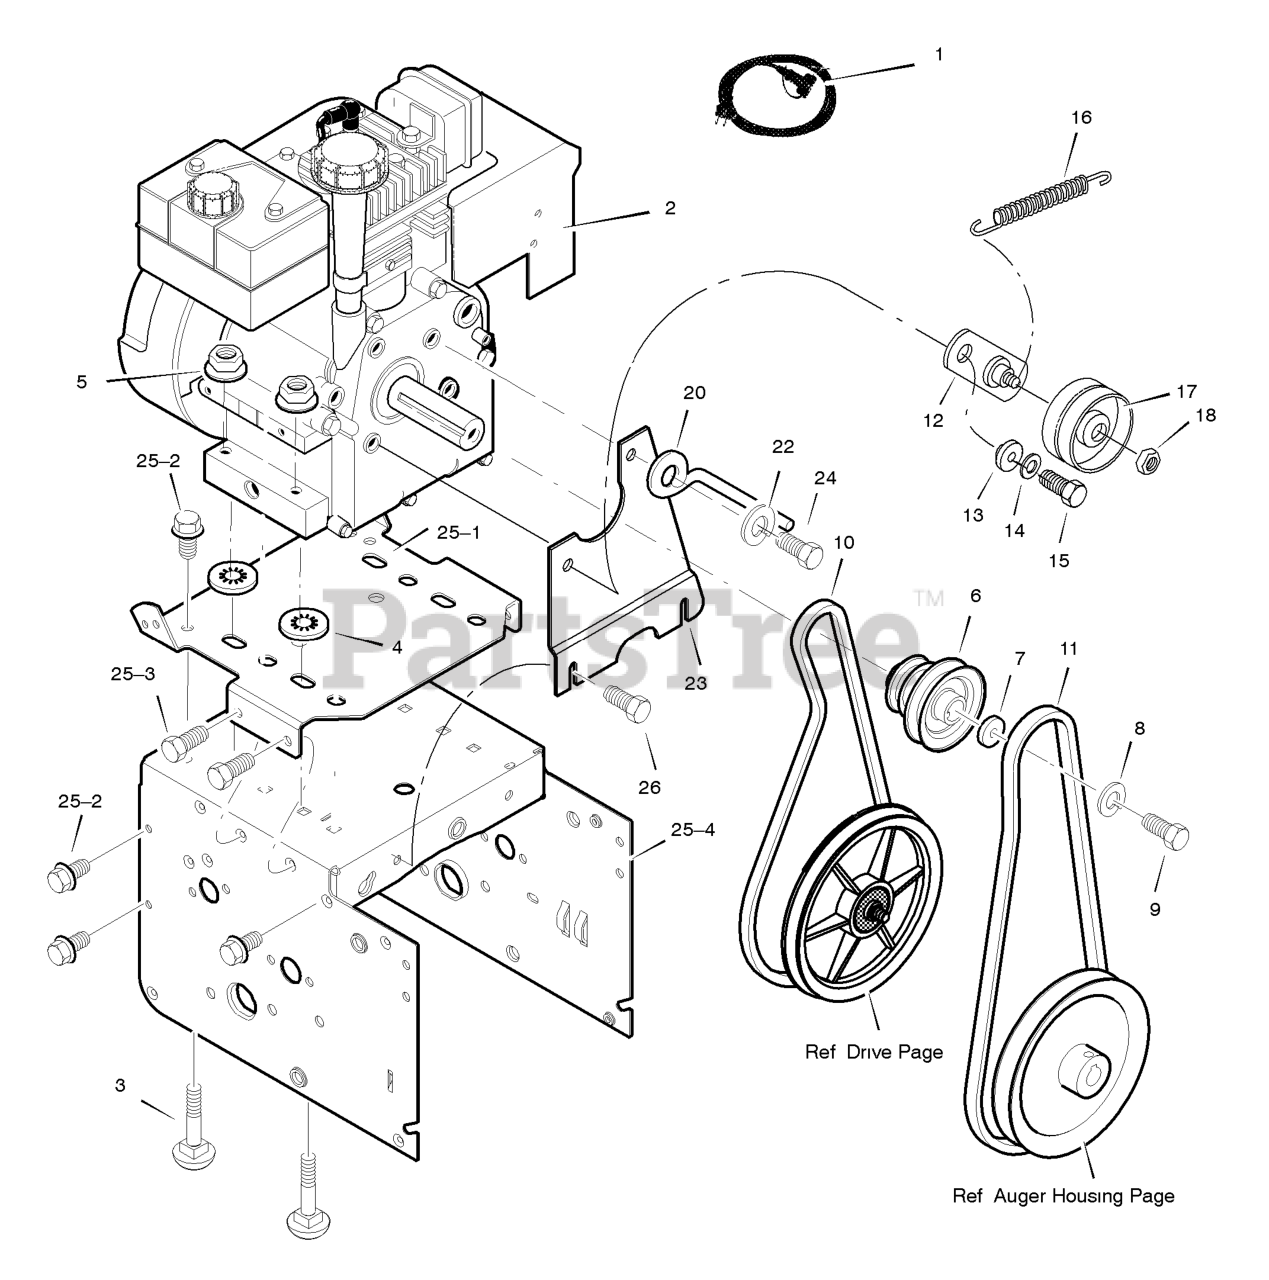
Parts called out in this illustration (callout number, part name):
1	CORD, Electric, 10FT. 110V
2	ENGINE
3	BOLT, CARRIAGE 5/16-18
4	RETAINER, PUSH
5	NUT 5/16-18
6	PULLEY, ENGINE
7	WASHER
8	WASHER
9	SCREW, 3/8-24 x 1.00
10	BELT, V
11	BELT, V
12	BRACKET ASSEMBLY, IDLER
13	BUSHING, IDLER BRACKET
14	WASHER
15	SCREW 5/16-24 X 1.00
17	PULLEY, IDLER
18	NUT, JAM 3/8-16
20	GUIDE, ROD BELT
22	WASHER, SPTLK .31X.58X.08
23	PLATE, ANTI VIBRATION
24	SCREW, 5/16-24 x 1.00
25	FRAME ASSEMBLY
25-1	PLATE, ENGINE MOUNT
25-2	SCREW 1/4-20 X .63
25-3	SCREW 5/16-18 X .50
25-4	FRAME, MOTOR BOX
